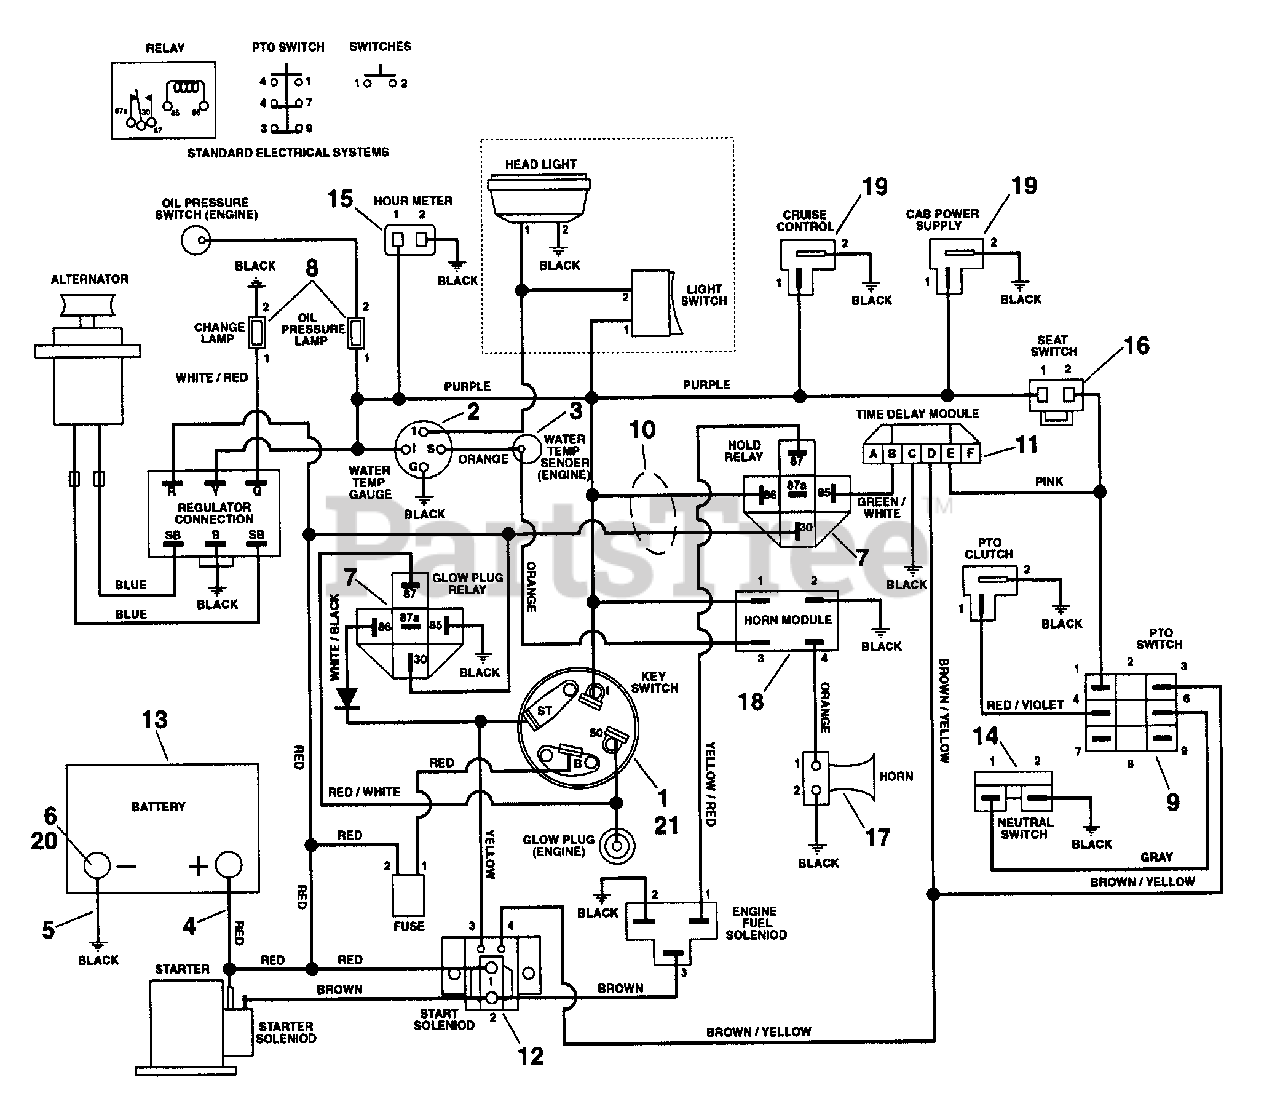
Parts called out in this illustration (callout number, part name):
1	Switch,Ignition(Diesel)
2	Gauge,Temperature
3	Sender,Temperature
4	Cable,Positive Battery
5	Cable,Negative Battery
6	Cover,Battery Terminal
7	Relay
8	Light,Indicator
9	Switch,Clutch with Retainer Ring
10	Wire Harness - Kubota
11	Module,Interlock, Delay 1801
12	Solenoid
13	Battery,12 V
14	Switch-Neutral Start N.O.
15	Hour, Meter
16	Switch-Seat
18	High Temp. Warning Module
19	Cover-Switch
20	Boot,Insulator
21	Ignition Key
